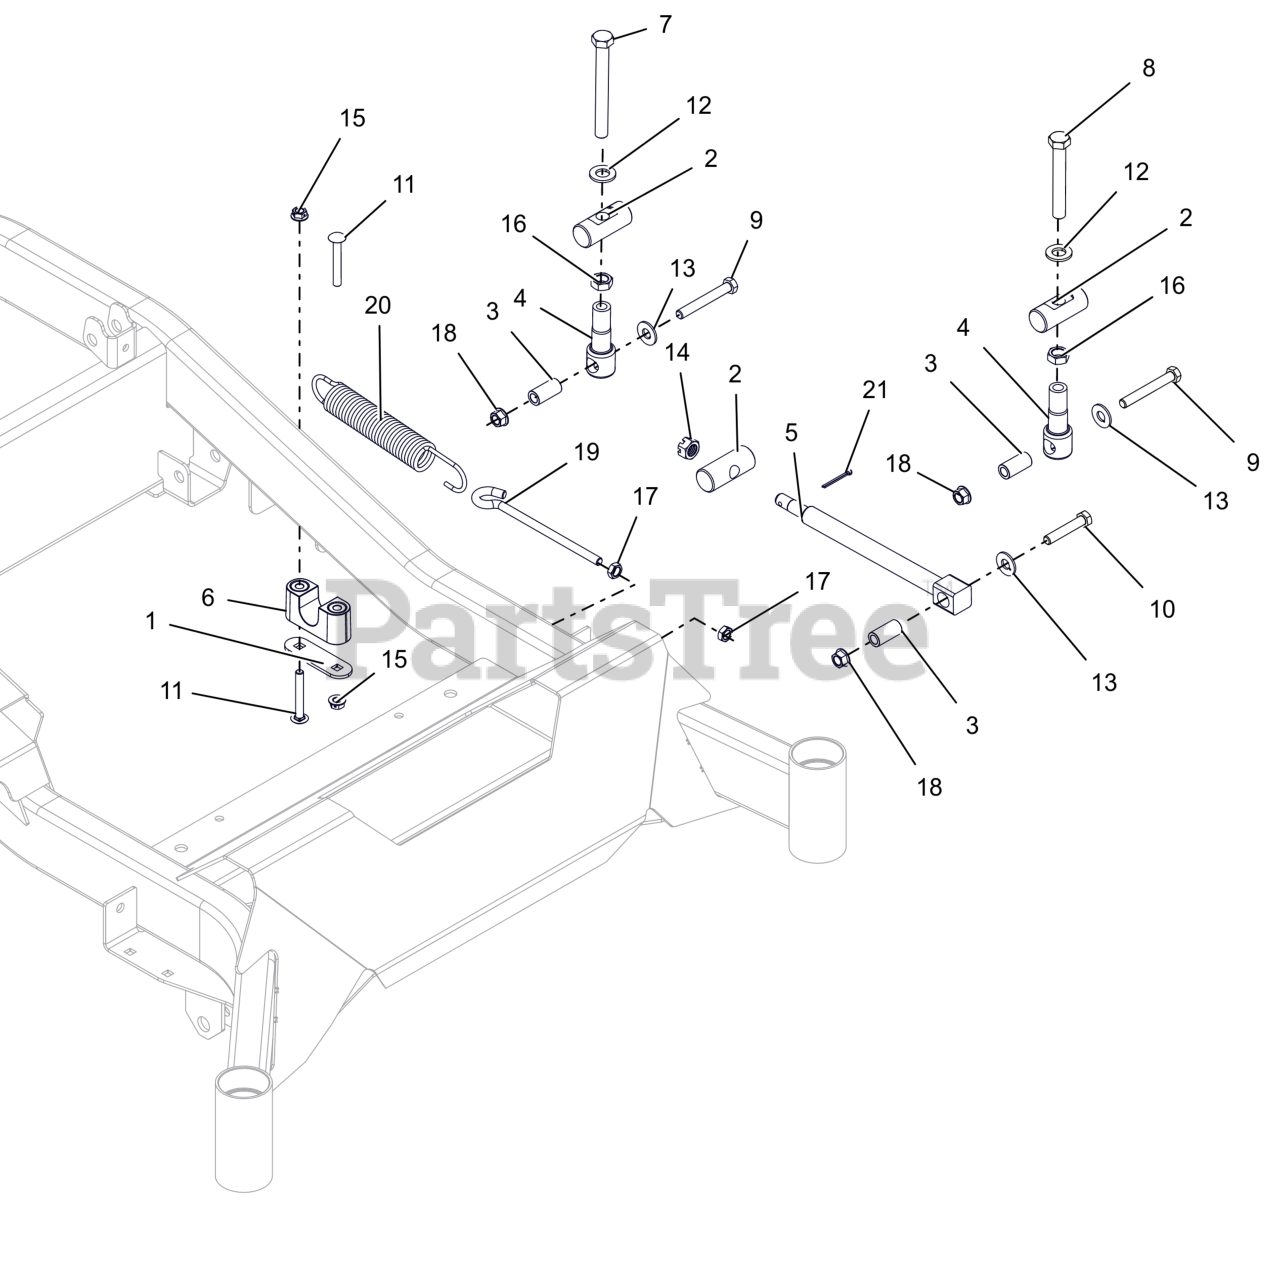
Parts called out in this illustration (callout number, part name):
1	PLATE, BEARING SUPPORT
2	PIN, DECK LIFT
3	SPACER, DECK LEVELING
4	LINK, DECK LIFT FORMED
5	DRAG,LINK-HD
6	ASM-BUSHING, DECK LIFT
7	@BLT-HEX .5-13-4.5GR8 FULL THD
8	BLT-HEX .50-13X3.50 GR5 FTH
9	BLT-HEX .38-16X2.75 GR8 YWZC
10	@BLT-HEX .38-16X2.00 GR5 YWZC
11	BLT-RDHDSQSHNK .31-18X2.25 YWZ
12	FLATWASHER 1/2 SAE HARD 15906
13	@WSHR-FL-STL.438X1.00X.083 YWZ
14	NUT-SL .50-13
15	@NUT-LK-CTR-FLG .31-18 YZ GR F
16	NUT-JAM .50-13 YWZC
17	NUT-HEX-JAM .375-16 YWZC
18	@NUT-LK-TOP-FLG .38-16 YWZC
19	BOLT,.38-16 X 5.25-.62 DIA EYE
20	SG-TENS .162X1.25X8.25 WLD 25
21	@PIN-CTR .12X1.25 EXTPRSQCT YZ
